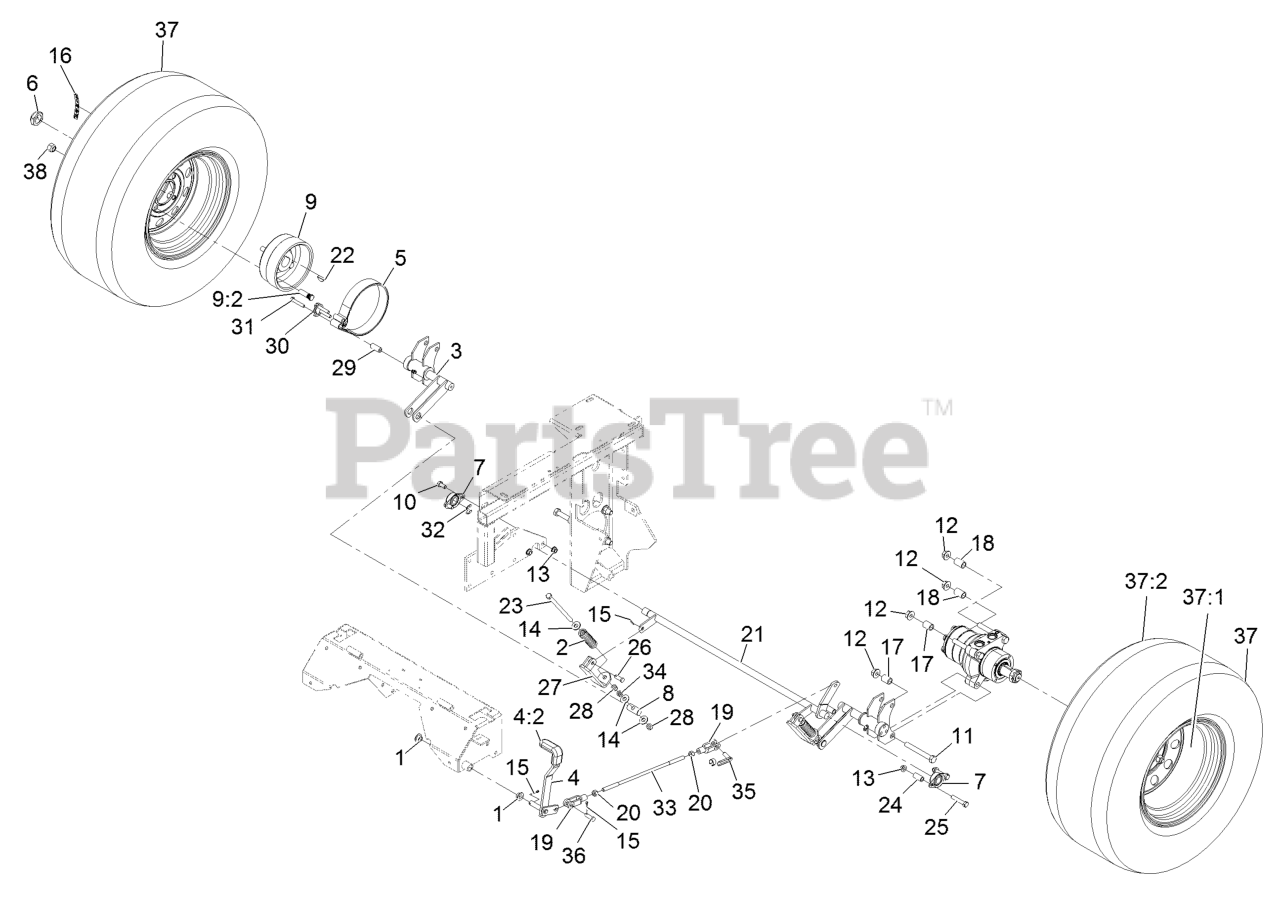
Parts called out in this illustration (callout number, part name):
1	BEARING-CONTROL
2	SPRING-COMPRESSION
3	BRAKE-NARROW
4	BRAKE LEVER AND GRIP ASM
4:2	GRIP-LEVER
5	BAND,BRAKE
6	LOCKNUT
7	BEARING-FLANGE, SIDE
8	PIN-TRUNION
9	HUB W/STUDS ASM
9:2	STUD-WHEEL
10	SCREW-HH
11	SCREW-HH
12	NUT-HHF
13	NUT-HHF, WHIZ
14	WASHER-FLAT
15	PIN-COTTER
16	DECAL-TORQUE, WHEEL HUB LUG
17	SPACER-WHEEL, SHORT
18	SPACER-WHEEL, LONG
19	YOKE-LINKAGE, BRAKE
20	NUT-HEX
21	SHAFT-BRAKE
22	KEY-WOODRUFF
23	BOLT-TAP, HH
24	SPACER-RETAINER, BRAKE
25	SCREW-HH
26	PIN-CLEVIS
27	LINKAGE-BRAKE, LOWER
28	NUT-LOCK, NI
30	RETAINER-BAND, BRAKE
31	SCREW-HH
33	ROD-BRAKE
34	NUT-JAM
35	PIN-SPRING, CLEVIS
36	PIN-CLEVIS
37	WHEEL AND TIRE ASM
38	NUT-LUG
